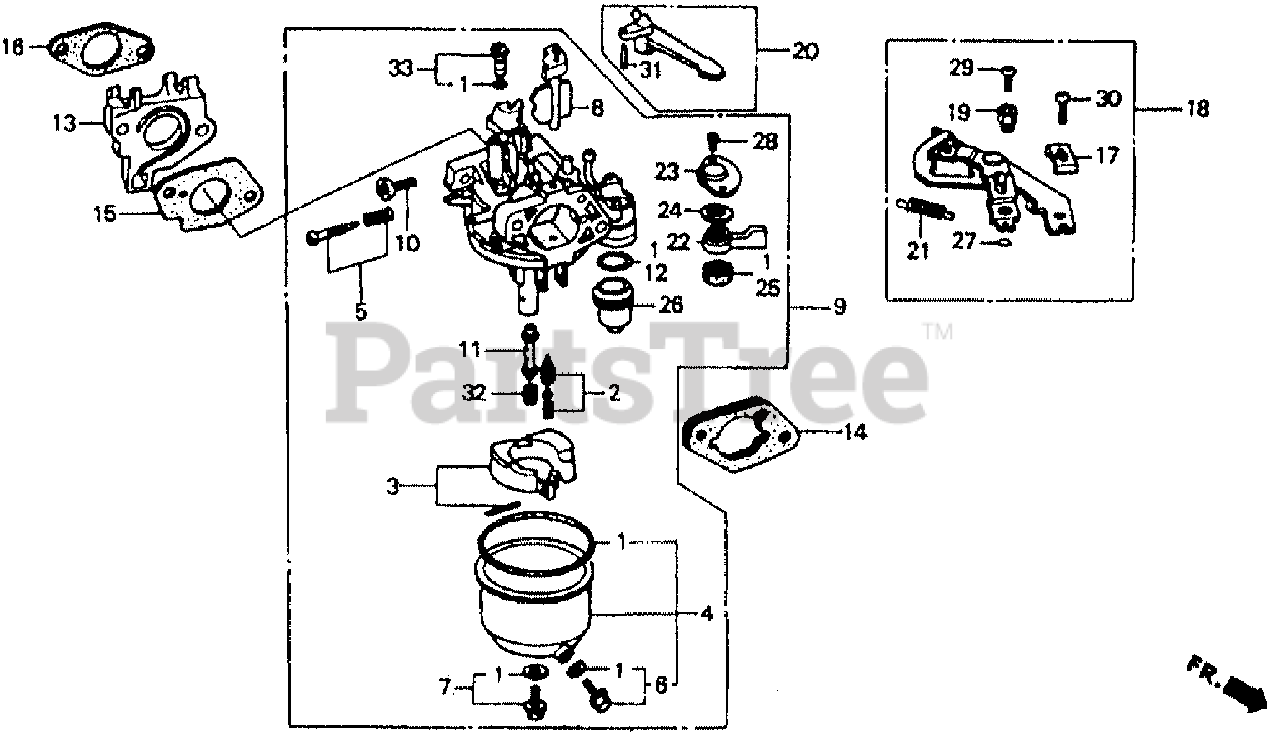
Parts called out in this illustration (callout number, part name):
1	GASKET SET
2	VALVE SET, FLOAT
3	FLOAT SET
4	CHAMBER SET, FLOAT
5	SCREW SET, PILOT
6	SCREW SET, DRAIN
7	SCREW SET B
8	CHOKE SET
9	CARBURETOR ASSY. (BE16B A)
9	CARBURETOR ASSY. (BE16B B)
9	CARBURETOR ASSY. (BE16B C) (Honda Code 4088662). (NOT AVAILABLE)
10	SCREW, THROTTLE STOP
11	NOZZLE, MAIN
12	GASKET, FUEL STRAINER CUP
13	INSULATOR, CARBURETOR
14	SPACER, CARBURETOR
15	GASKET, CARBURETOR
16	GASKET, INSULATOR
17	HOLDER, CABLE
18	STAY ASSY., CHOKE CONTROL (Honda Code 2831667). (REMOTE)
19	HOLDER, WIRE
20	LEVER, CHOKE (STD)
21	SPRING, RETURN
22	LEVER, VALVE
23	PLATE, LEVER SETTING
24	SPRING, VALVE LEVER
25	GASKET, VALVE
26	CUP, FUEL STRAINER
27	CIRCLIP (5MM)
28	SCREW, PAN (3X8)
29	SCREW, PAN (4X6)
30	SCREW-WASHER (5X16)
31	PIN, SPRING (2X12)
32	JET, MAIN (#88)
32	JET, MAIN (#90)
32	JET, MAIN (#92)
32	JET, MAIN (#95)
